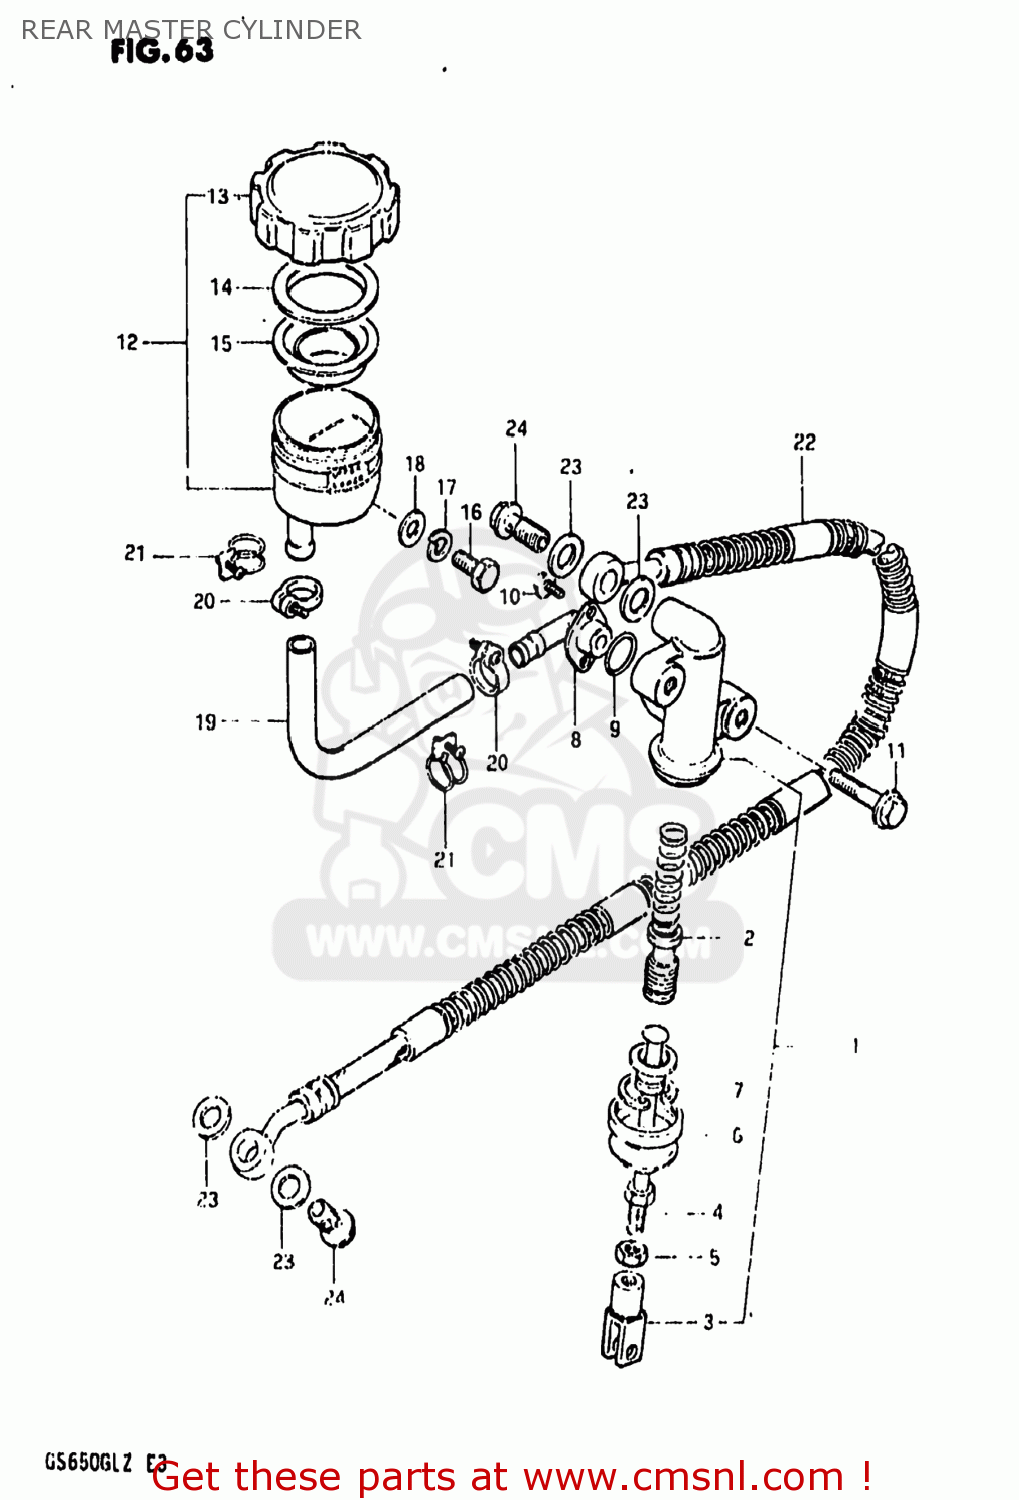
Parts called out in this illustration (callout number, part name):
1	CYLINDER ASSEMBLY,REAR MASTER
2	PISTON/CUP SET
3	YOKE
4	ROD,REAR MASTER CYLINDER
5	NUT
6	BOOT
7	CIRCLIP
8	CONNECTOR,HOSE
9	O RING
10	SCREW
11	BOLT
12	TANK ASSEMBLY,RESERVOIR
13	CAP
14	PLATE,DIAPHRAGM
15	DIAPHRAGM
16	BOLT, UPPER
17	LOCK WASHER
18	WASHER
19	HOSE,RESERVOIR TANK
20	CLAMP
21	CLAMP
22	HOSE,REAR BRAKE
23	WASHER
24	BOLT,UNION
